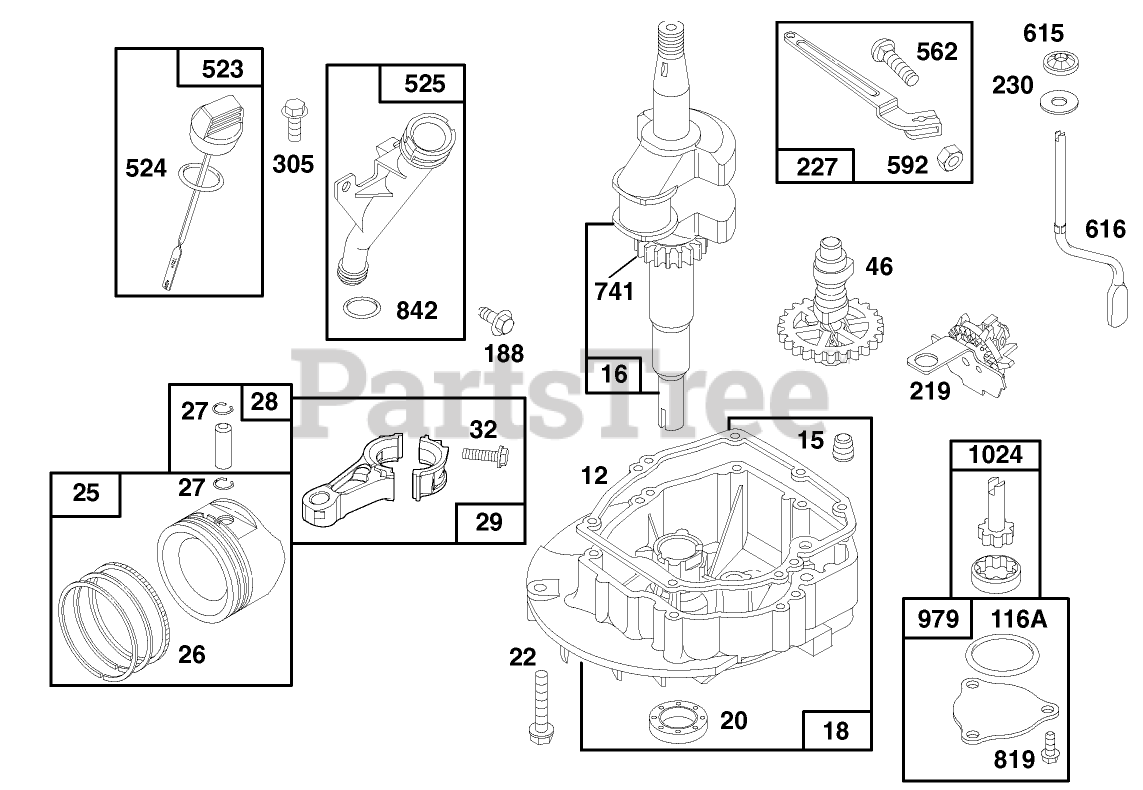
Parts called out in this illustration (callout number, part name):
12	ENGINE BASE GASKET
15	PIPE PLUG
20	SEAL-OIL
25	STD PISTON ASSEMBLY
27	PISTON PIN LOCK
28	PIN ASM - PISTON
29	CONNECTING ROD
116A	O RING SEAL
219	GOVERNOR/OIL SLINGER
227	GOVERNOR LEVER ASSEMBLY
305	SCREW - HEX HEAD
524	O-RING
562	GOVERNOR LEVER BOLT
592	HEX NUT
819	SCREW - SEM
842	O-RING
979	OIL PUMP COVER
1024	OIL PUMP
